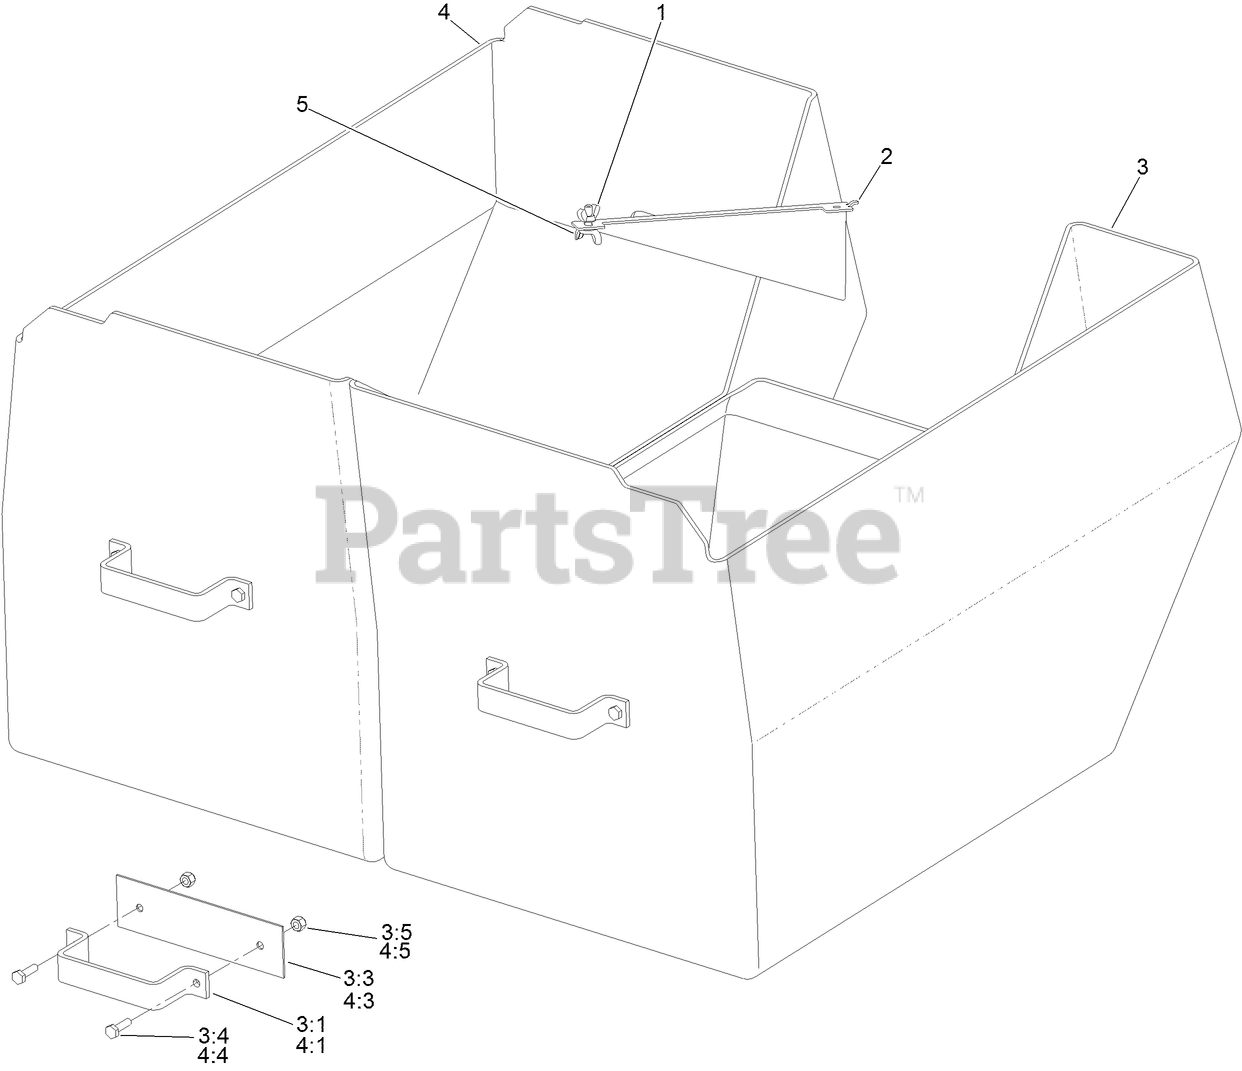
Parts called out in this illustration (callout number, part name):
1	NUT-WING
2	DEFLECTOR-GRASS
3	RH TUB ASM
3:3	PLATE-REINFORCEMENT
3:4	SCREW-HH
3:5	NUT-LOCK, NI
4	LH TUB ASM
4:3	PLATE-REINFORCEMENT
4:4	SCREW-HH
4:5	NUT-LOCK, NI
5	SCREW-WING
